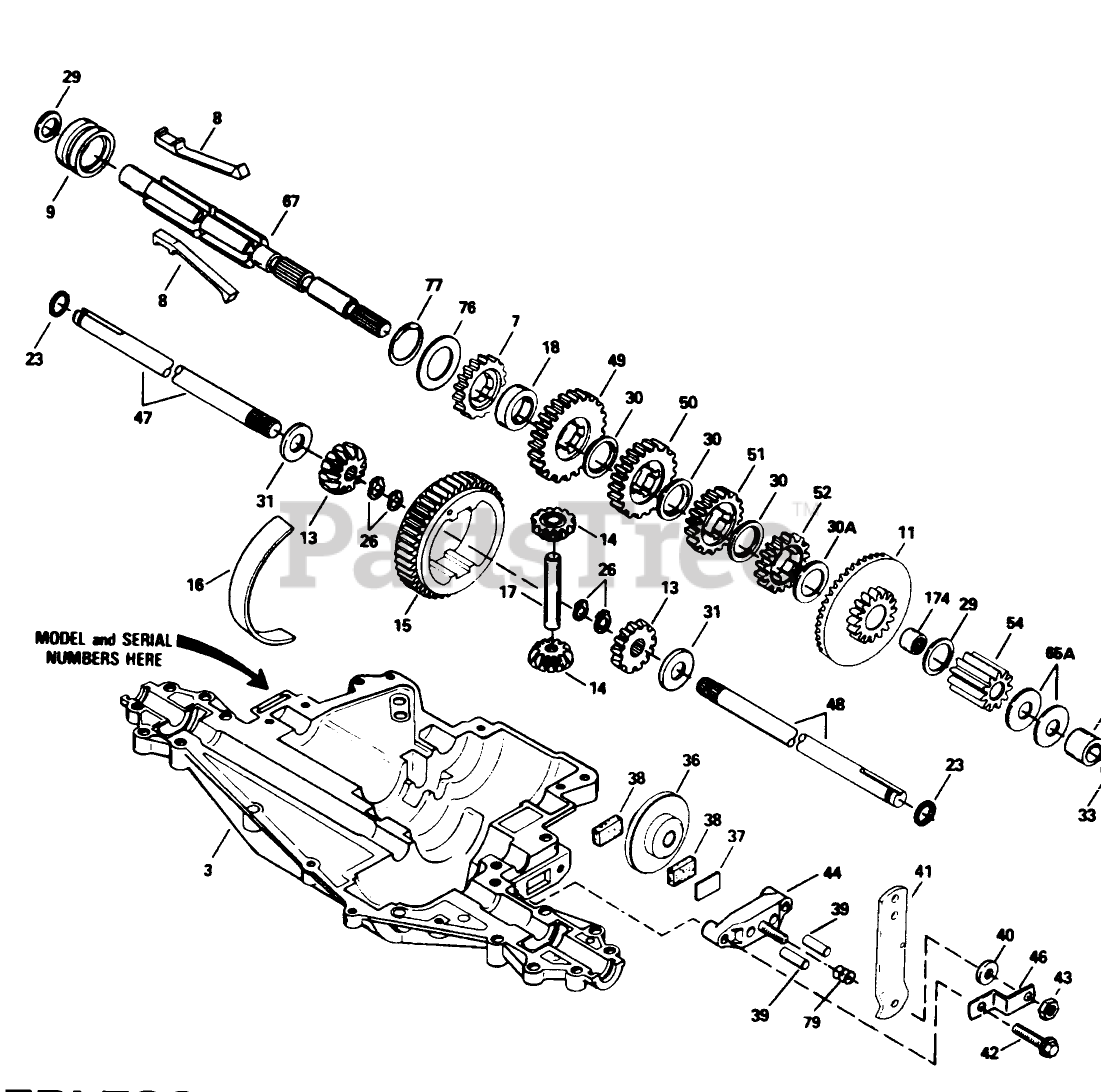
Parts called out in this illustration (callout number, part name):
3	Transaxle Case
7	Gear-Spur (22 teeth)
8	Shift Key
9	Shift Collar
11	Bevel Gear Bearing (44/16 Teeth) (Incl. Ref. #174)
13	Gear Bevel
14	Gear Pinion
15	Gear-Ring
16	Bearing Strip
17	Drive Pin
18	Neutral Spacer
23	Ring-Seal
26	Retaining Ring (pkg of 2)
29	Washer
30	Washer
30A	Washer
31	Washer
33	O-Ring
34	Bushing
36	Brake Disk
37	Brake Pad Plate
38	Brake Pad
39	Dowel Pin
40	Washer
41	Brake Lever
42	Ring Set (.020 O S)
43	Locknut
44	Nozzle-Carburetor
46	Bracket
47	Axle (16-13/16" Ig.)
48	Axle (11-5/8" long)
49	Gear-Spur, 35 Teeth
50	Gear-Spur 27 Teeth
51	Spur Gear (19 Teeth)
52	Gear-Spur 20 teeth
54	Spur Gear (11 Teeth)
65A	Washer
67	Shifter Brake Shaft
76	Washer
77	Inverted Retaining Ring
79	Piston ASM (.020 O S)
174	Needle Bearing
